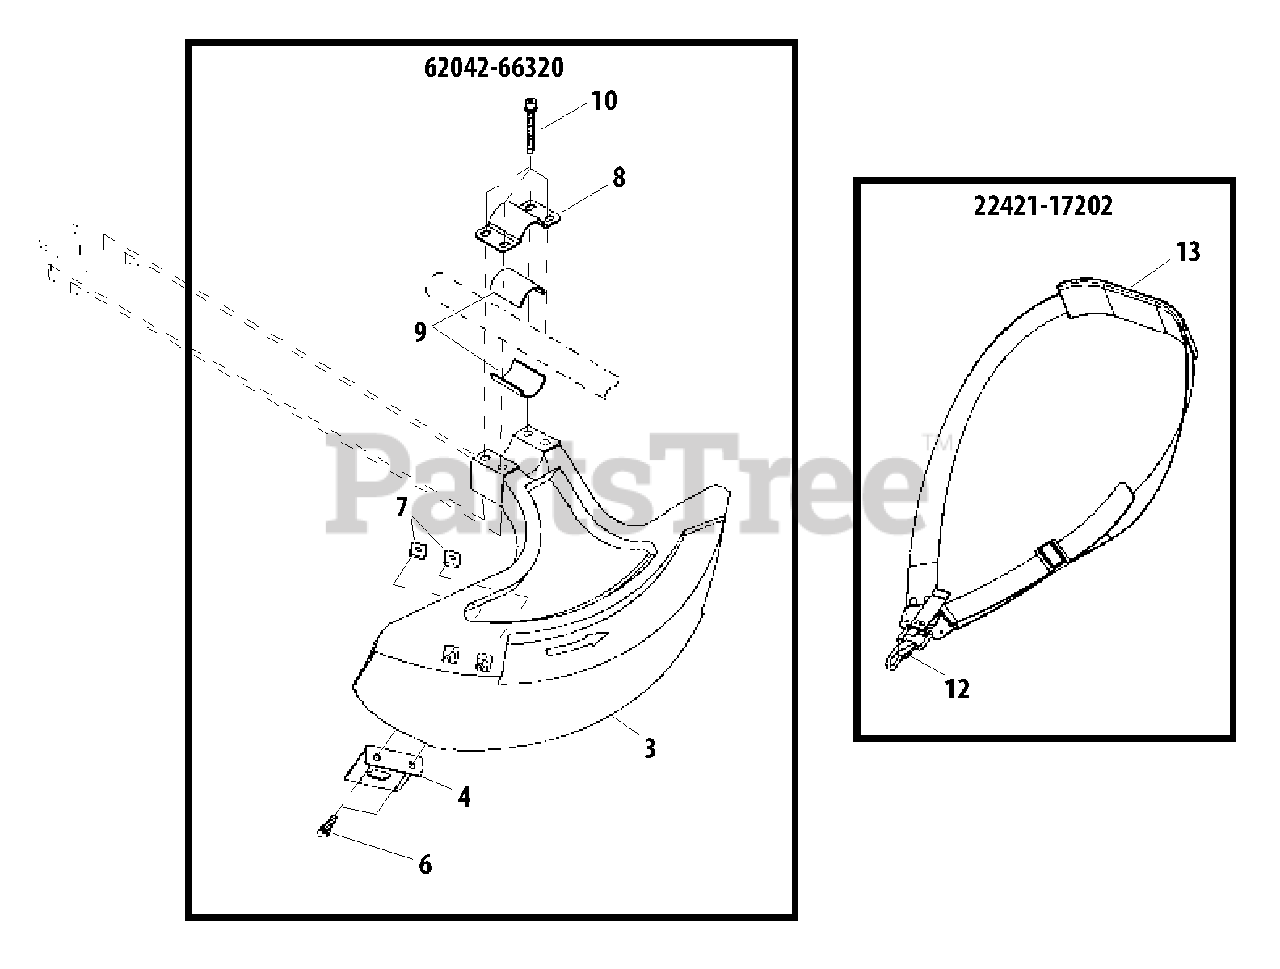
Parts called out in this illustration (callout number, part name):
3	SHIELD
4	CUTTER
6	BOLT M5×22
7	NUT M5
8	CLAMP, UPPER
9	SPACER
10	BOLT M5×45
12	HOOK, SNAP
13	PAD, SHOULDER
22421-17202	HARNESS ASSY, SHOULDER
62042-66320	GUARD ASSY
